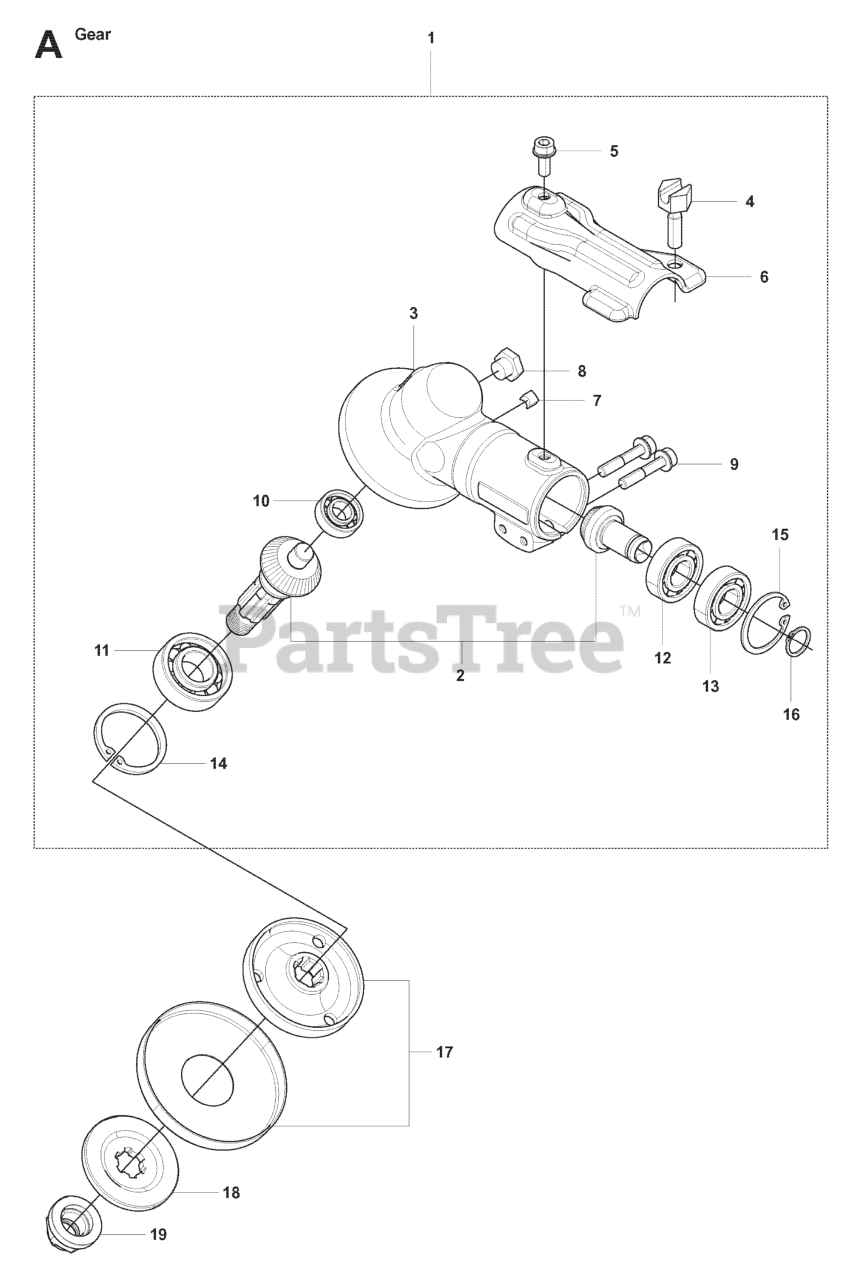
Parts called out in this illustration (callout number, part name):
1	%GEAR CASE ASSY
2	SPARE PARTS KIT
5	SCREW
6	RP HOLDER
10	BALL BEARING 24X9X1/609ZR
11	BALL BEARING
13	BALL BEARING
14	RETAINING RING
15	RETAINING RING SGH 28
16	SEEGER CLIP
17	RP CARRIER
18	RP FLANGE
